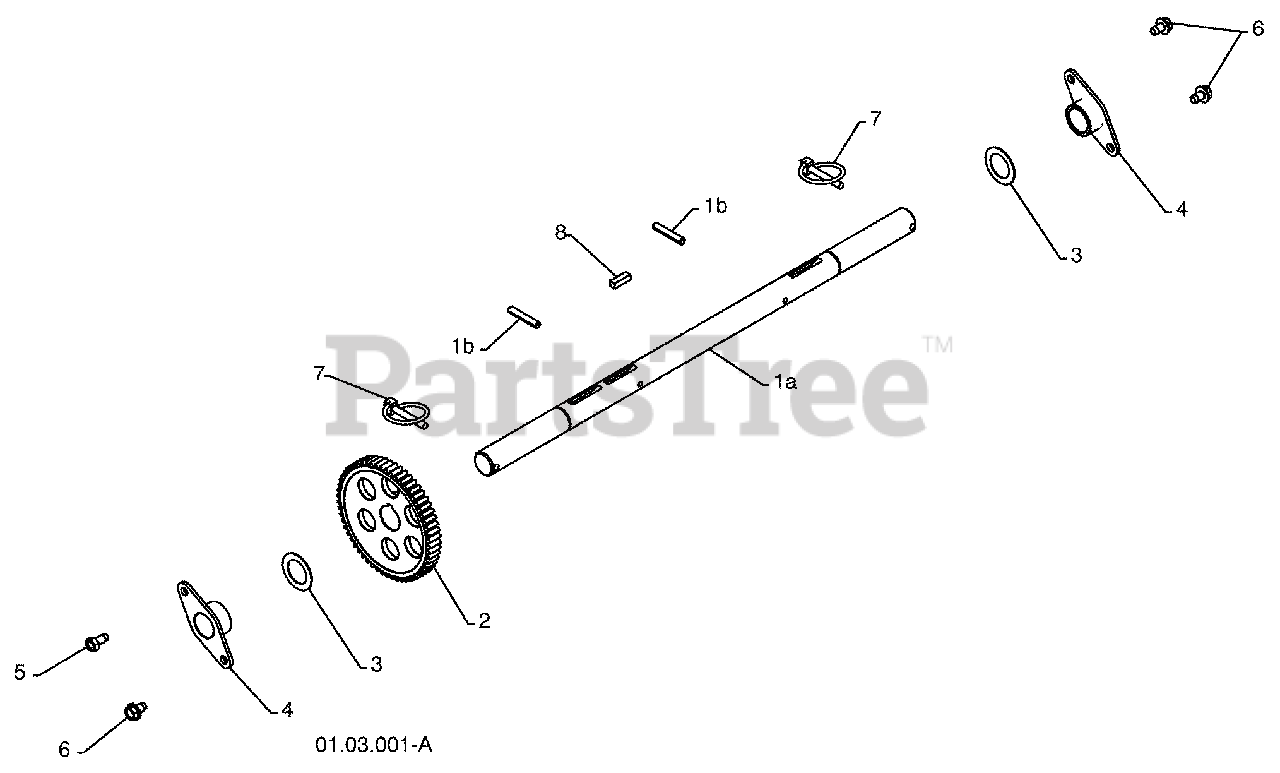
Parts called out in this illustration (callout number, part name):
1	(assy of 1a,1b) AXLE ASSEMBLY
2	GEAR
3	THRUST WASHER
4	AXLE BEARING
5	SCREW 5/16-18 X .625
6	BOLT 5/16-18 X .500
8	SQUARE KEY
